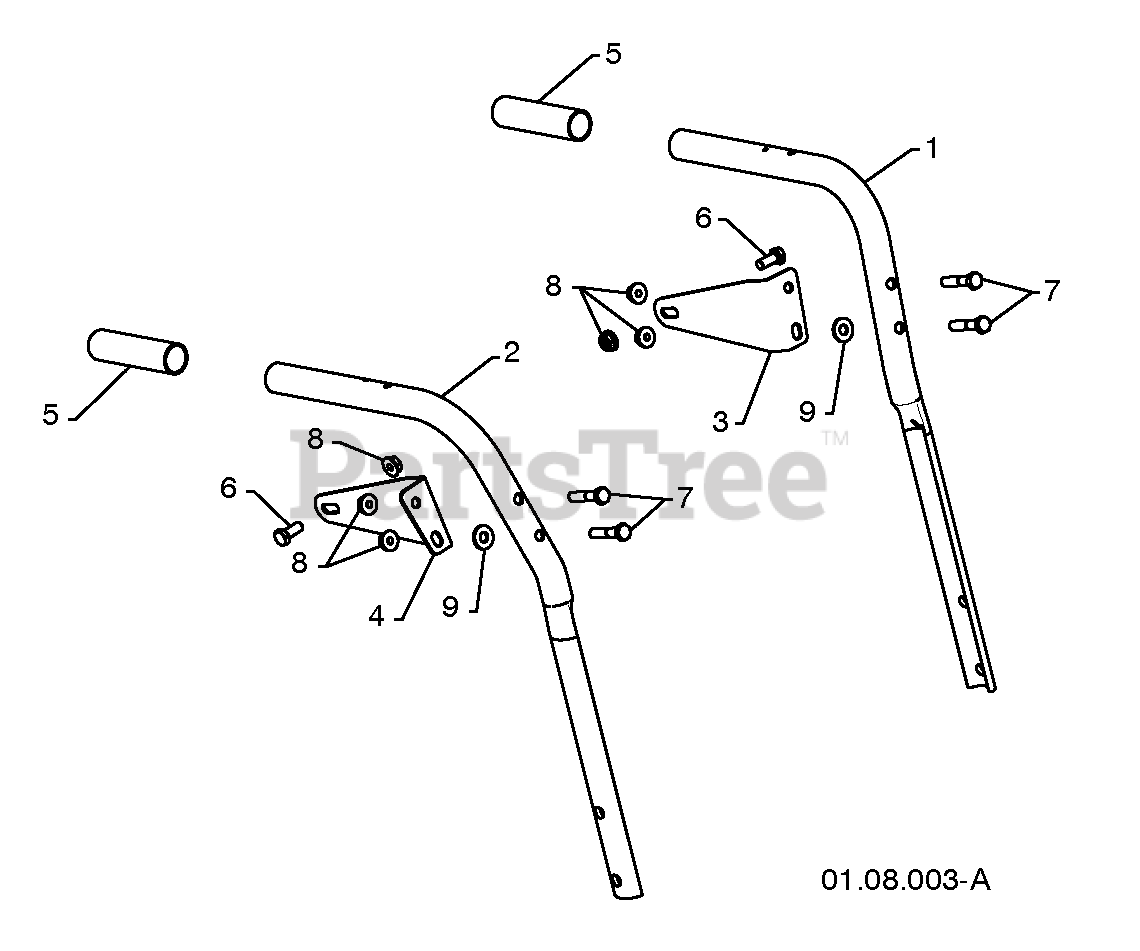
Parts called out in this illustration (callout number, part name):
1	PLOW HANDLE LH
2	PLOW HANDLE RH
3	PANEL BRACKET LH
4	PANEL BRACKET RH
5	HANDLE GRIP
6	SCREW 5/16-18 X .750
7	SCREW 5/16-18 X 1.50
8	NUT 5/16-18
9	WASHER
